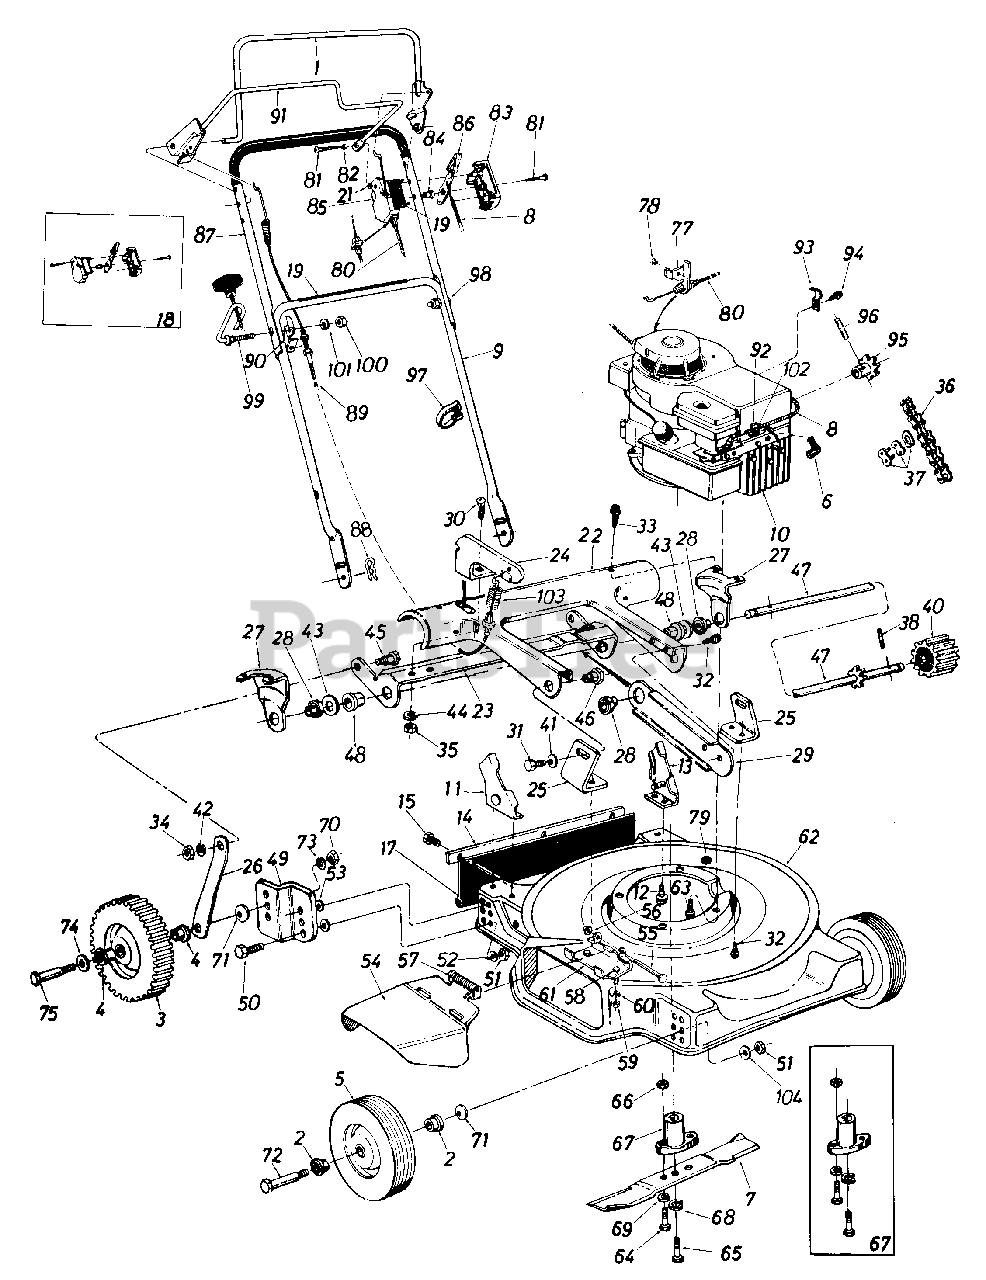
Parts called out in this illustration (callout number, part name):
1	HANDLE ASSY-CONTROL-LH
2	BEARING-FORTIFLEX
3	WHEEL ASSY W/TIRE
4	BEARING-BALL
5	WHEEL ASSY W/TIRE-7 X 1.5 T LINE
6	INSULATOR-SPARK PLUG
7	BLADE-22IN
8	WIRE-THROTTLE
9	LOWER HANDLE
10	Engine
11	BRACKET ASSY-HDLE
12	SCREW-HEX WASH HD 5/16-18X1/2
13	BRACKET ASSY-HDLE
14	STRIP-RETAINING
15	SCREW-HEX WASH HD
17	FLAP-RR
18	KIT-THROTTLE CONTROL
21	WASHER-FL-.203 ID X .41 OD X .040
22	COVER-PINION PIVOT
24	ARM-ENGAGEMENT
25	BRACKET-PIVOT LH
27	BRACKET-AXLE
28	BEARING-BALL
29	SUPPORT-BEARING
30	BOLT-CARRIAGE 1/4-20 X .50
31	SCREW-HEX 3/8-16 X .50
32	SCREW-HEX B-TAP 1/4 X .38
33	SCREW-HEX WASH HD
34	NUT-HEX 5/16-18
35	NUT-HEX 1/4-20
36	#48 CHAIN 1/2 PITCH X 50 LINKS
37	#48 MASTER LINK 1/2 PITCH TYPE 11
38	PIN-SPRING SPIR 3/16 X 1.25
40	PINION-DRIVE
41	WASHER-BELL .400 ID X .88 X .060
42	WASHER-LOCK-5/16
43	WASHER-FL-.531 X .930 OD X .050
44	LOCK WASHER 1/4 DIA
45	SCREW-SHLD .437 DIA X .162
46	NUT-SHLD
47	SHAFT-PINION
48	BEARING-BALL
49	BRACKET-WHEEL
50	SCREW-HEX 3/8-16 X .75
51	NUT-HEX 3/8-16
52	WASHER-BELL .400 ID X .88 X .060
53	WASHER-FL-.385 ID X .62 OD X .033
54	DEFLECTOR ASSY-CHUTE
55	PIN-PIVOT
57	SPRING-TORSION
58	SCREW-HEX 1/4-20 X .50
59	NUT-HEX 1/4-20
60	LOCK WASHER 1/4 DIA
61	PLATE-ADAPTER
62	DECK ASSEMBLY-22IN
63	SCREW-HEX
64	SCREW-HEX SPECIAL 5/16-24X1.0
64	SCREW-HEX SPECIAL 5/16-24 X 1.0
65	SCREW-HEX 3/8-24 X 2.25
66	NUT-5/16-24
67	KIT-BLADE ADAPTER
68	WASHER-HDL 3/8
69	WASHER-LOCK-5/16
70	NUT-HEX 3/8-16
71	WASHER-BELL .400 ID X .88 X .060
72	SCREW-SHLD .498 DIA X 1.450-THD
73	WASHER-LOCK-3/8
74	WASHER-FL-.531 ID X .93 OD X .090
75	BOLT-SHLD
77	BRACKET-CABLE
80	WIRE-THROTTLE
81	SCREW-TRUSS MACH
83	PANEL HALF-CONTROL
84	PIN-CONTROL DISC
85	PANEL HALF-CONTROL
86	LEVER-THROTTLE CONT-REV
87	HANDLE-UPPER
88	PIN-INTERN COT-5/16 DIA
89	CABLE-CLUTCH
90	BRACKET-CABLE MTG
91	HANDLE ASSY-CONTROL
92	CLAMP-CONDUIT
93	CLAMP-CASING
94	SCREW-HEX B-TAP #10 X .38
95	SPROCKET-10T
96	PIN-SPRING SPIR 3/16 X 1.00
97	TIE-CABLE
98	BOLT-CARRIAGE-CURV 5/16-18 X 1.38
99	SCREW-RECOIL HANDLE GUIDE
100	NUT-HEX 5/16-18
101	WASHER-LOCK-5/16
102	SCREW-HEX WASH HD AB-TAPP #8 X .38
103	SPRING-COMPRESSION
104	WASHER-BELL
